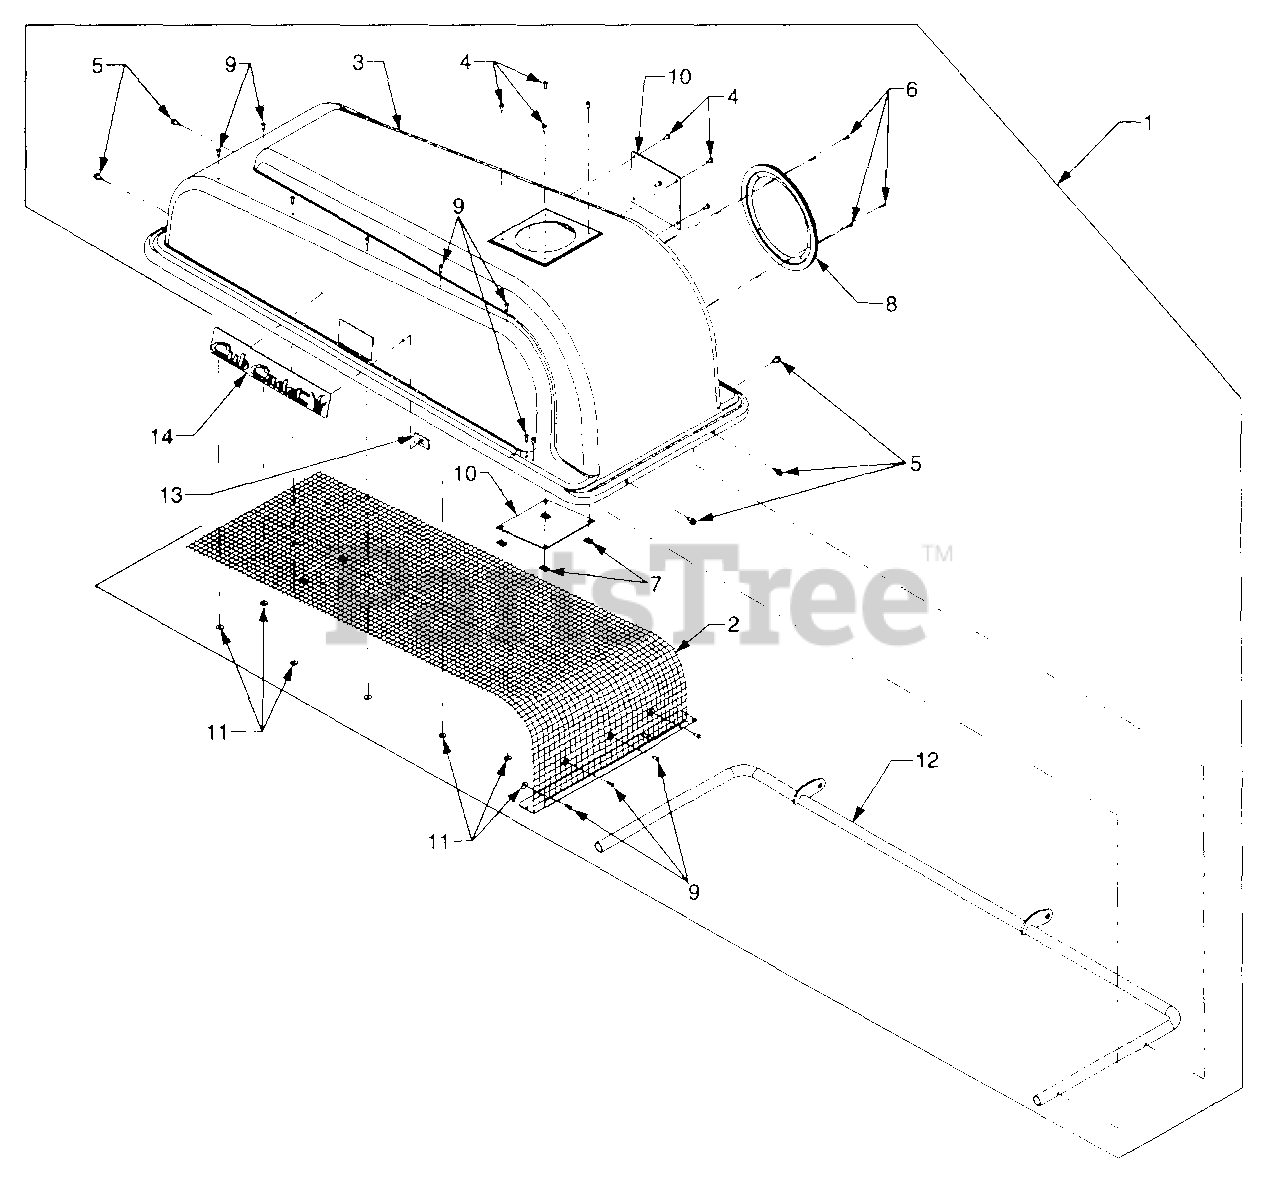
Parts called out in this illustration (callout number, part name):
1	Cover Assembly
2	Screen and Mtng. Brkt. Ass'y.
3	Cover
4	Screw, Truss Hd. Mach. 10-24 x .50
5	Screw, Hex Wash. Hd. Tapp 1/4-14 x .625
6	Screw, Truss Hd. Tapp 6-20 x .625
7	Speed Nut, 'U' Type, 10-24
8	Seal, Tube, 7.10 ID
9	Rivet, Pop, .187 x .45
10	Plate, Plastic
11	Washer, Flat, .194 x .62 x .063
12	Bracket Assembly, Cover Hinge
13	Speed Nut, Push On
14	Decal, Cub Cadet
